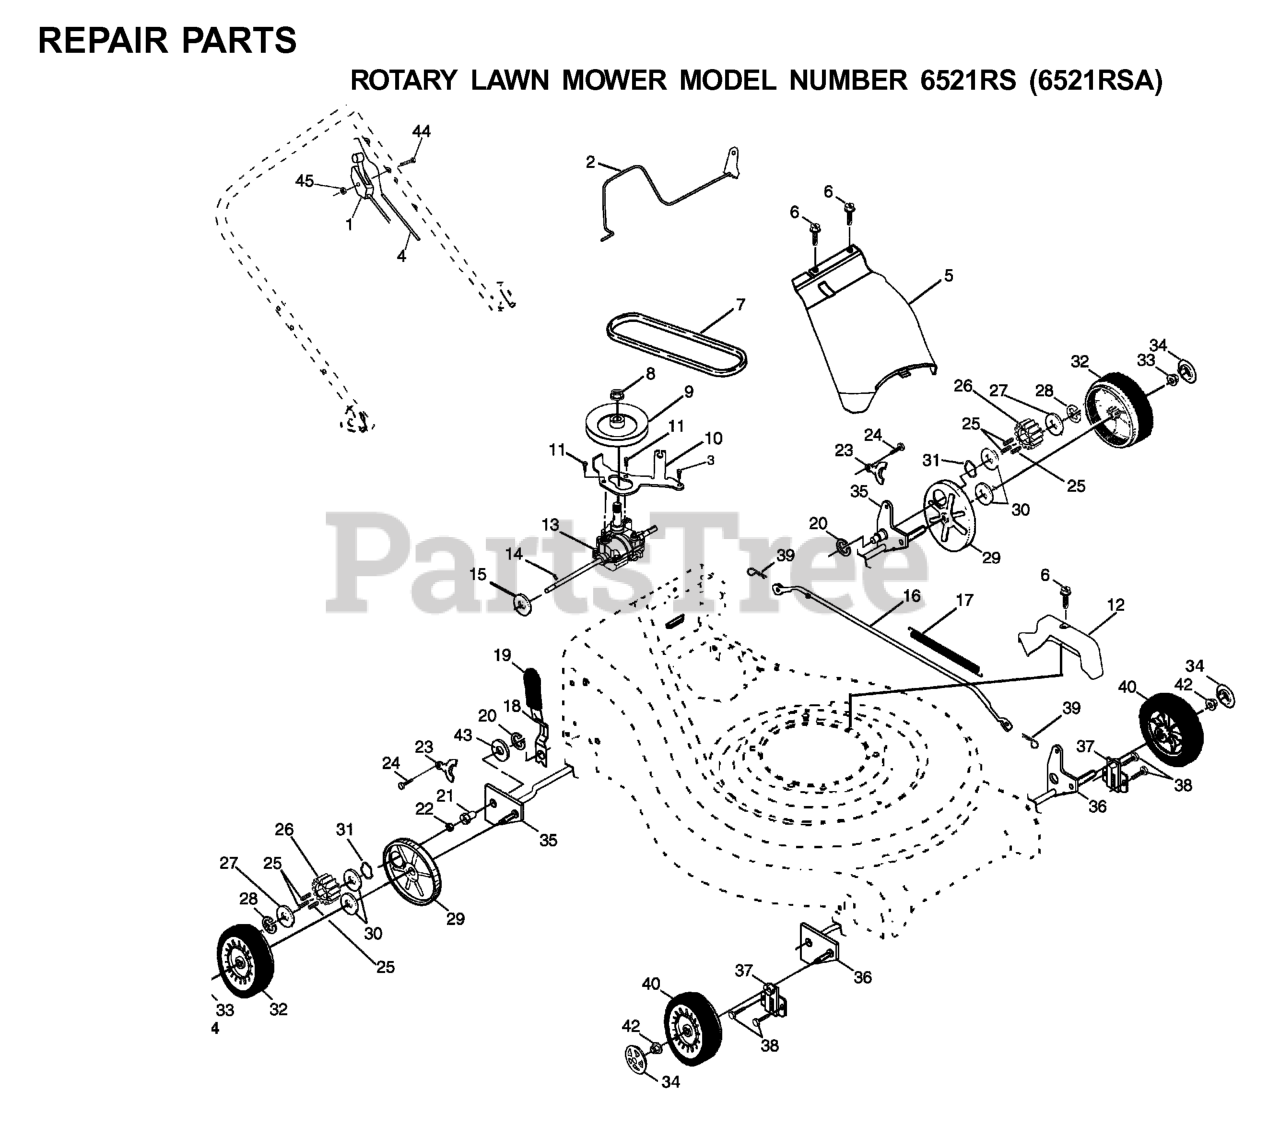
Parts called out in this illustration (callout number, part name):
4	DRIVE CABLE
5	DRIVE COVER
8	FLANGED LOCKNUT 3/8-16 ZINC
9	PULLEY DRIVEN
10	BELT KEEPER BRKT
11	Screw, Hex Washer Head #10-24 x .668
12	PIVOT ROD COVER
13	TRANSMISSION ASM.
14	PIN.SPRING.THRUST
15	THRUST WASHER
16	ROD CONNECTING
17	SPRING
18	SPRING
19	KNOB
21	RP BEARING SUPPORT
22	BEARING, BALL
23	BRACKET
25	PAWL.DRIVE.ETCHED
26	PINION.DRIVE.WALK
28	E-RING 7/16 RE
29	DUST SHROUD PM
30	WASHER FLUT
31	WAVE WASHER
33	NUT
34	CAP.HUB.BLACK.WALK
35	SHAFT ASSY
36	SHAFT ASSY
37	RETAINER.FRONT.SHAFT
39	RETAINER CLIP
42	HEX FLANGE LOCKNT
43	WASHER.ZINC.PLATED
44	SCREW 1/4-20 X 2.12
45	LOCK NUT
